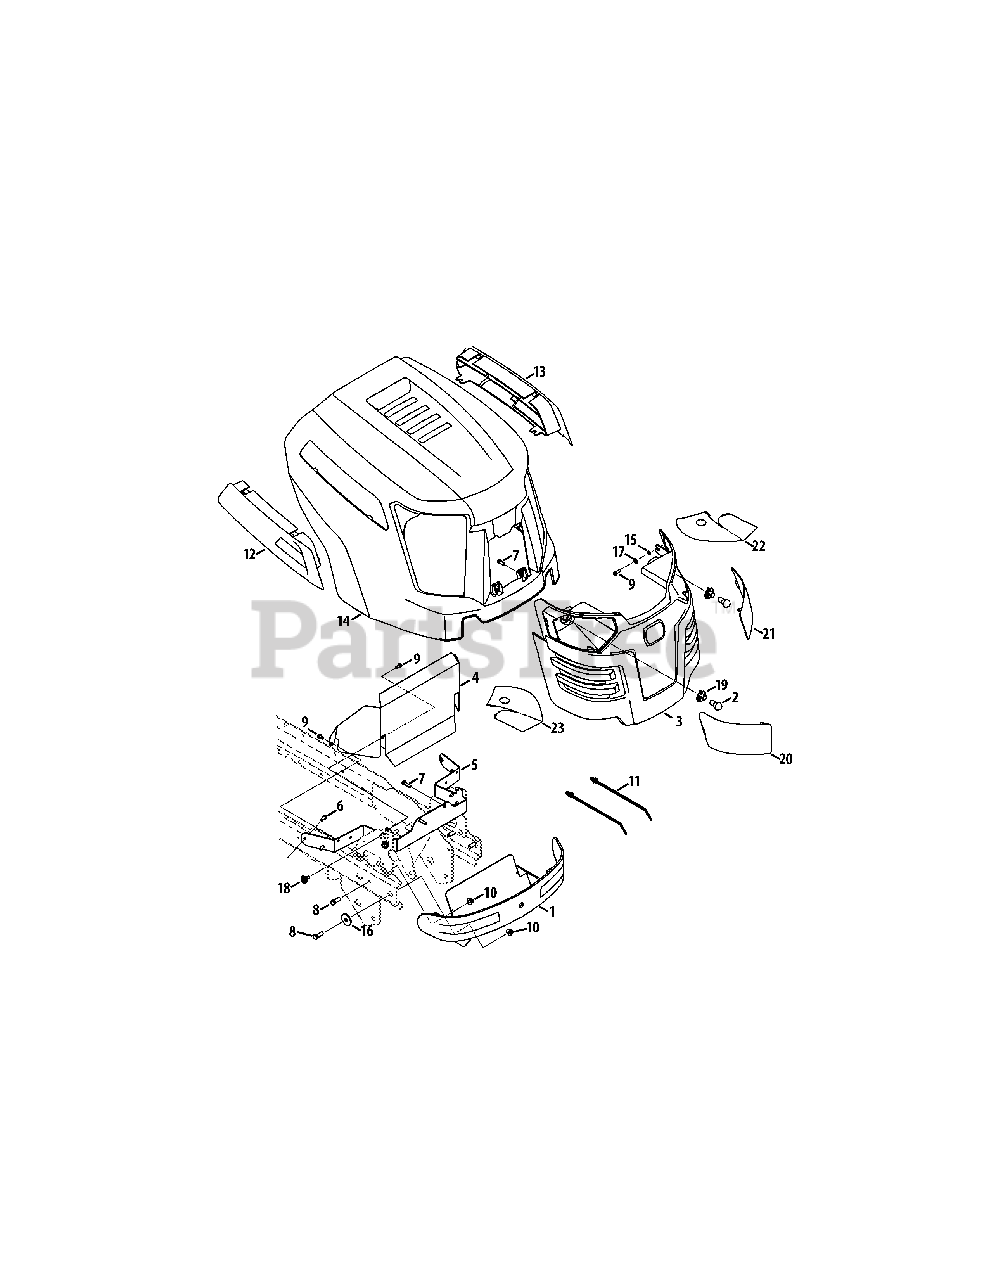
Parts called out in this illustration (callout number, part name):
3	Grill
4	Heat Shield
5	Hood Pivot Bracket
6	Hex Washer Screw, 1/4 x .750
7	Hex Washer Screw, 5/16-14 x 1.00
8	Hex Screw, 3/8-16 x 1.00
9	Hex Washer Screw, 1/4-20 x 0.500
10	Flange Lock Nut, 3/8-16
11	Cable Tie, 7.5
12	RH Hood Scoop
13	LH Hood Scoop
14	Hood
15	Lock Washer, 1/4
16	Flat Washer, .390 x 1.500 x .134
17	Flat Washer, .271 x .630 x .065
18	Shoulder Screw, 5/16-18 x .43 x .29
19	1/4-turn Socket
20	RH Hood Lens
21	LH Hood Lens
22	Left Lens Reflector Label
23	Right Lens Reflector Label
